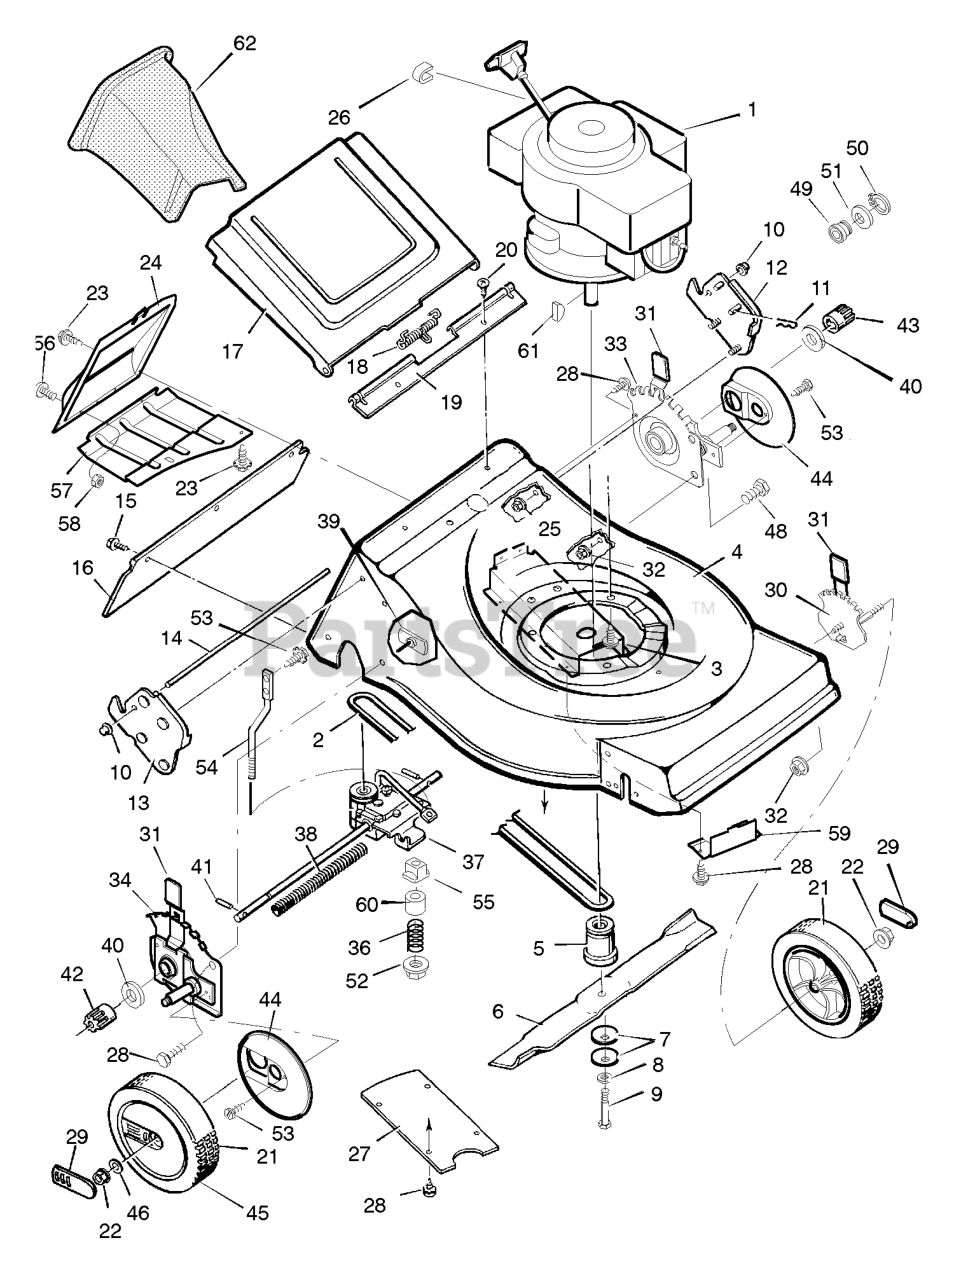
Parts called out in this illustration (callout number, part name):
1	Engine *
2	Belt, Drive
3	Bolt, Engine
4	Housing
5	Adapter, Blade
7	Washer, Belleville
10	Push On Cap
11	Pin, Hair
12	Handle Bracket, Left
13	Handle Bracket, Right
14	Rod, Door Pivot
16	Deflector, Rear
17	Door, Rear
18	Spring, Torsion
19	Spacer, Door
21	WHEEL & TIRE ASSEMBLY, White, 8"
22	Nut
24	Transmission, Cover
25	Nut, Flange
26	Stop, Rope
27	Cover, Belt
29	Hub Cap, Front
30	Height Adjuster, Front
32	Nut, Flange
33	Height Adjuster, Left Rear
34	Height Adjuster, Right Rear
36	Spring, Extension
37	Transmission TIM .50
38	Shield, Axle
39	Nut, Special
40	Washer, Thrust
41	Pin, Drive
42	Pinion, Right
43	Pinion, Left
44	Cover, Dust
45	Wheel, Drive - White
46	Washer, Thrust
48	Bolt
49	Bearing and Retainer
50	Ring, Retaining
52	Locknut
54	Support, Spring
55	Bushing
56	Screw
57	Cover, Lower
59	Cover, Front Belt
61	Key, Woodruff
62	Plug, Mulcher
